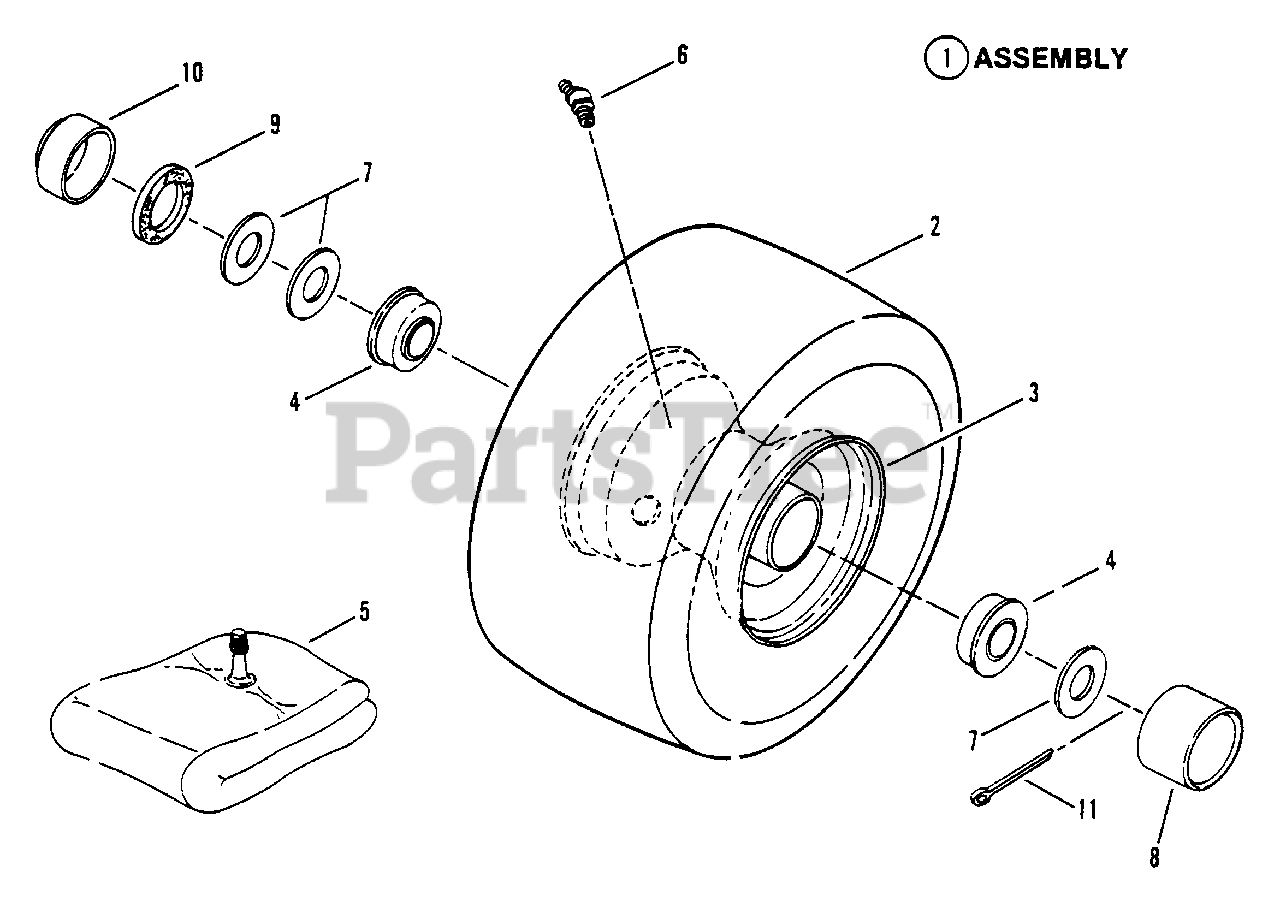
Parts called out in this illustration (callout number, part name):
1	ASSEMBLY, Front Tire & Rim (11.0")
2	TIRE, Pneumatic 11.0 x 4.0 x 4
3	RIM
4	BEARING, Ball
5	TUBE, Inner
6	FITTING Lube
7	WASHER
8	CAP, Hub
9	SEAL, Felt
10	CAP, Dust
11	PIN, 5/32 x 1" Cotter
